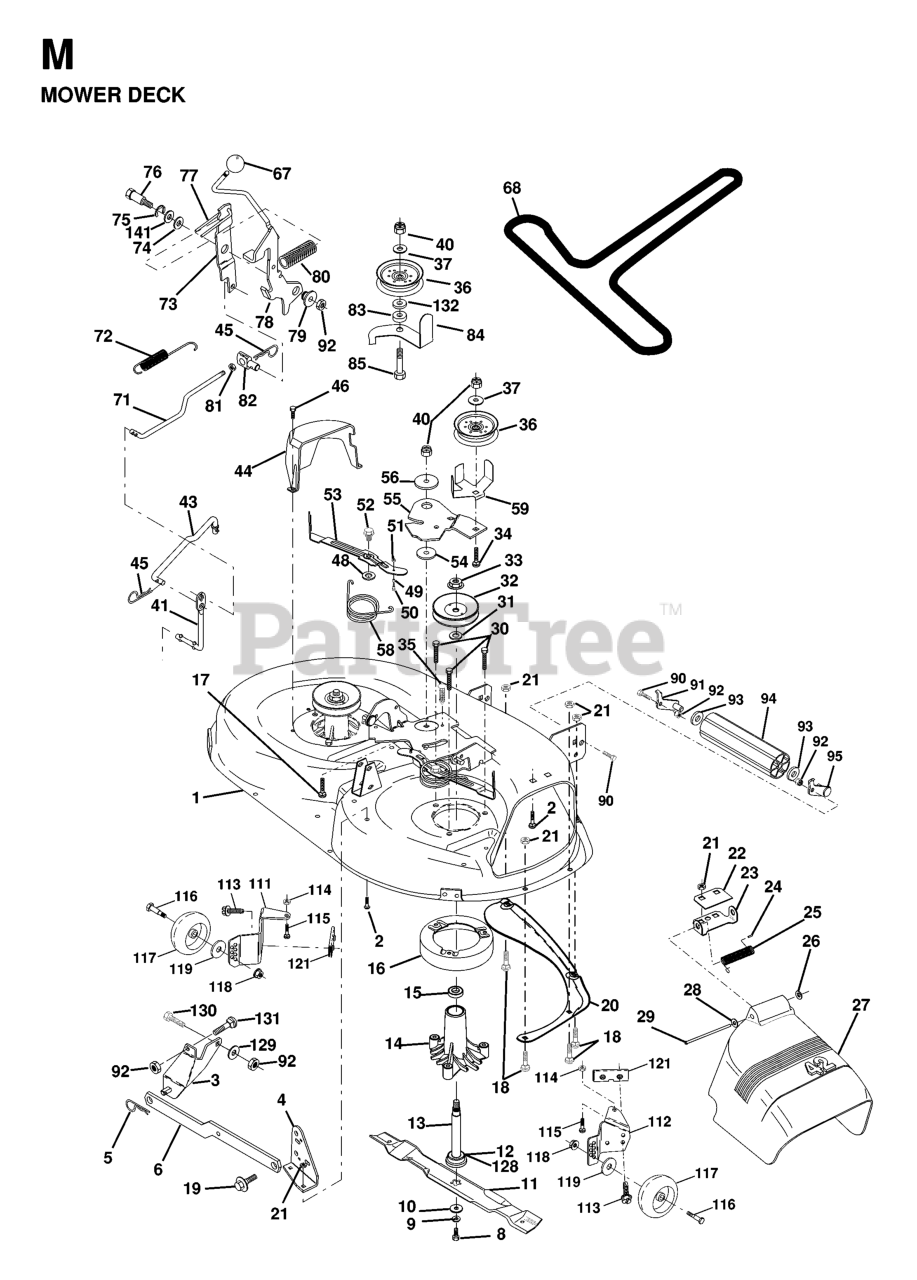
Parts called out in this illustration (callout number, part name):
1	DECK 42"
2	RP BOLT 5/16-18 X3/4 ZN/YEL GR
3	BRKT ASM SWAY BAR
4	BRKT DECK SW BAR
5	RETAINER-SPRNG RB
6	REAR SUSP ARM
8	BLADE BOLT
9	LOCKWASHER
10	WASHER.BLADE
11	BLADE 42", YTH 160
12	BEARING.BALL.#6204.(MANDREL)
13	SHAFT ASM VENT
14	HOUSING.MANDREL.VENTED (MACHD)
16	STRIPPER
17	BOLT
18	BOLT
19	BOLT SHD 5/16-18
20	BAFFLE.VORTEX
21	LOCKNUT
22	STIFFENER BRACKET
23	DEFLECTOR BRACKET
24	CAP-SLEEVE LT
25	SPRING TORSION
26	NUT PUSH M
27	SHIELD.DEFLECTOR.MOWER.42".BLK
28	Washer 11/32 x 5/8 x 16 Ga SD
29	ROD.HINGE
30	SCREW THDROL ROLLING WASHER HD
31	WASHER
32	PULLEY/MANDREL
33	NUT
35	FASTENER.XMAS.TREE
36	FLAT IDLER PULLEY
37	WASHER
43	CLUTCH ROD
44	GUARD MANDREL LH BLACK
45	RETAINER M
46	SCREW.1/4-20X5/8
49	ROLLER ASSY
52	BOLT.SHOULDER.5/16-18
53	ARM ASM PAD BRAD
54	HARDENED WASHER
55	ARM IDLER 42" MOWER LT/YT
56	SPACER RETAINER
59	GUARD, BELT
67	KNOB.CONTROL.7/16
71	CLUTCH ROD
72	RETURN SPRING
73	ARM CLUTCH SECONDARY
77	KEEPER SPRING
78	CLUTCH LEVER ASSY
79	BUSHING.FLANGE.E-RING.GROOVE
80	SPRING-CLUTCH (2 2 PW01)
81	NUT
82	TRUNNION.ADJUSTABLE.3/8-16
84	KEEPER.BELT.IDLER
85	BOLT
90	BOLT
91	BRACKET LH (A)
92	NUT
93	Washer 1 17/32 X 7/8 X 16 Ga
94	NOSE ROLLER
95	BRACKET RH (B)
111	BRACKET WHEEL GAUGE LH 42" DK
112	BRACKET WHEEL GAUGE RH 42" DK
113	SCREW.THDROL.5/16-18X3/4.TTY
114	NUT
115	BOLT.CARR.5/16-18X1/2
116	BOLT, SHOULDER
117	WHEEL GAGE DONUT
118	LOCKNUT
119	WASHER.5/16.FLAT.STE.STD.
121	BRACKET.EXTRUDED.GAGE.WHEEL
128	WASHER FELT
129	WASHER
130	BOLT
131	BOLT D
132	Washer 13/32 x 1-3/8 x 13 Ga.
